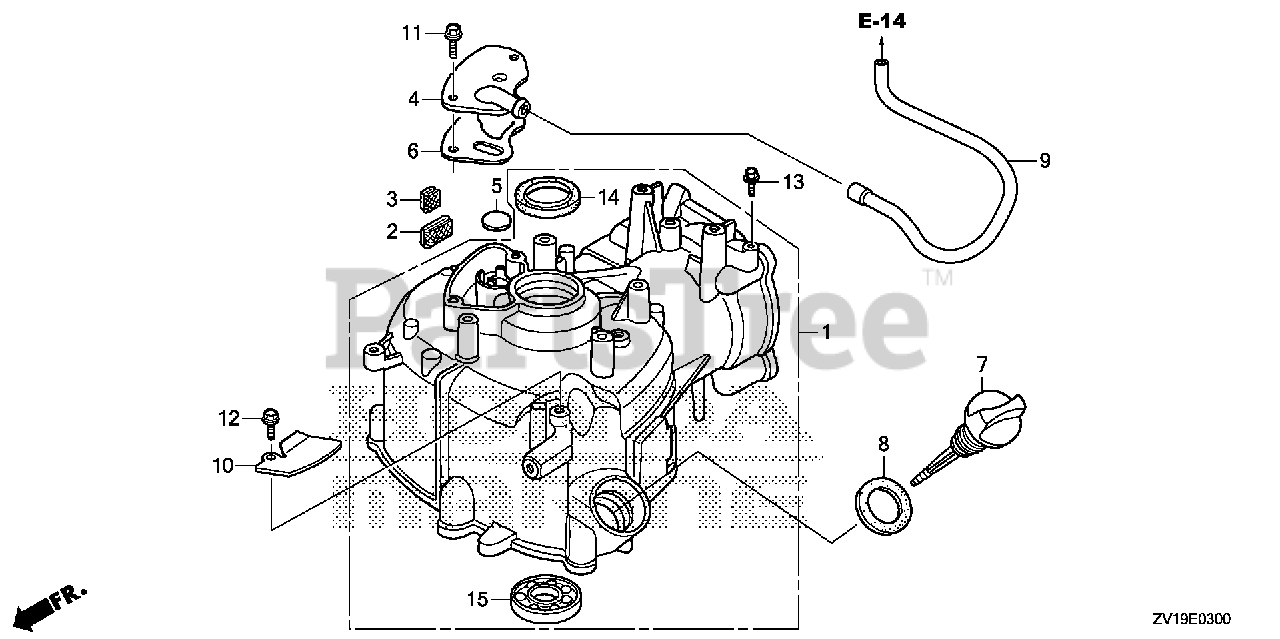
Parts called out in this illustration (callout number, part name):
1	CYLINDER ASSY. *NH8* (DARK GRAY)
2	FILTER A, BREATHER
3	FILTER B, BREATHER
4	CAP, BREATHER CHAMBER
5	VALVE, BREATHER
6	GASKET, BREATHER CAP
7	CAP, OIL FILLER
8	GASKET, OIL FILLER CAP Use up to Engine SN 1257294.
9	TUBE, BREATHER
10	CLAMP, BREATHER TUBE
11	BOLT, FLANGE (6X12) (CT200)
12	BOLT, FLANGE (5X10)
13	BOLT, FLANGE (5X10) (CT200)
14	OIL SEAL (25X38X7)
14	OIL SEAL (25X38X7) (ARAI)
15	BEARING, RADIAL BALL (6205)
